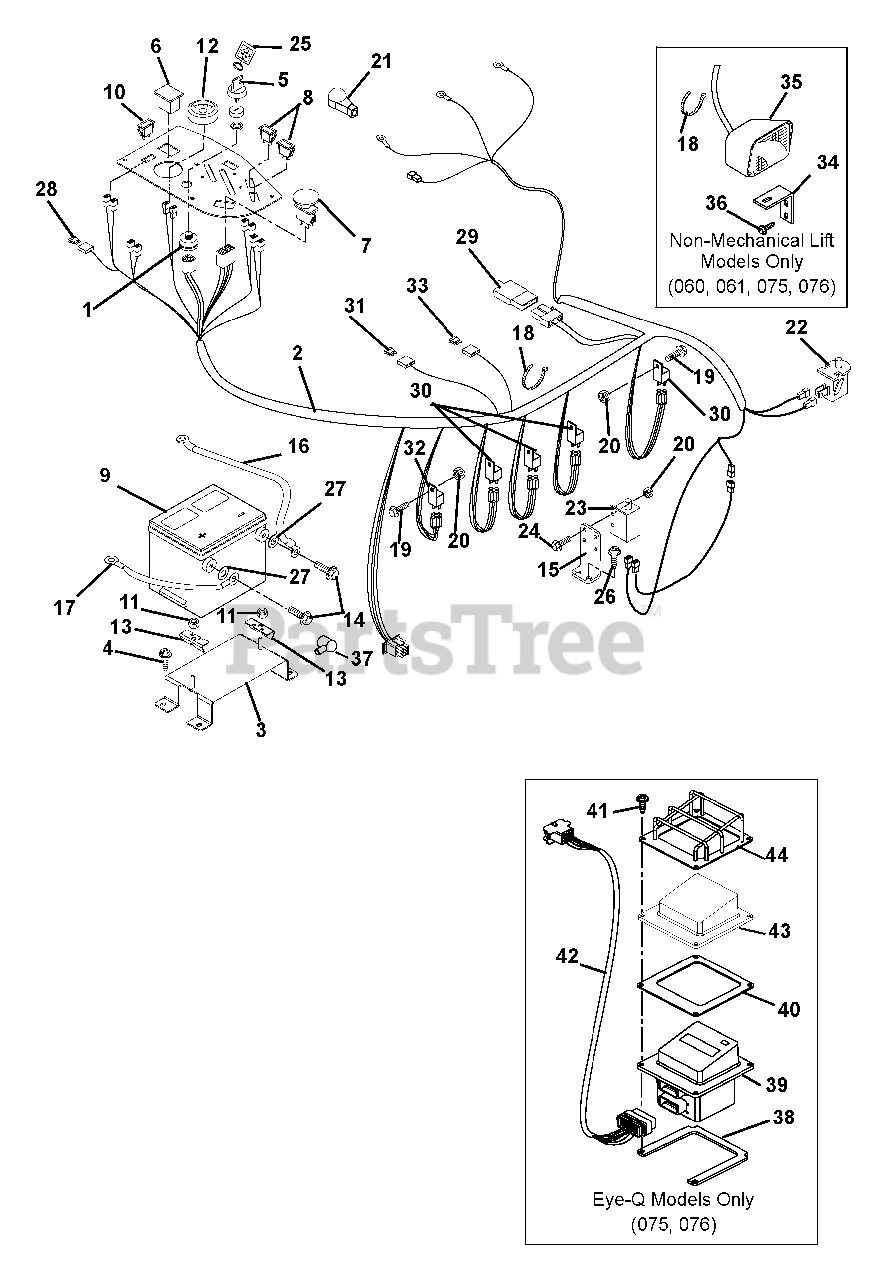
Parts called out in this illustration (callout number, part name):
1	Switch, Ignition (Diesel)
2	Harness, Wiring (Diesel)
3	Weldment, Battery Support
4	Screw-Tapping .38-16 x .75 Hex Washer Head
5	Key-with Cap
5	Ignition Key Set
6	Plug
6	Hour Meter
7	Switch-Clutch With Retainer Ring
8	Light-Indicator Kit
9	Battery with Tube
10	Switch, Light
10	Switch, Blank
11	Nut-Locking-Top-Flange .31-18
12	Gauge, Temperature
13	Bracket, Battery Hold-Down
14	Bolt-Hex .25-20 x .75 Grade 5
15	Mount, Safety Switch
16	Positive Cable
17	Cable, Negative Battery
18	Cable Tie
19	Screw-Machine 10-24 x .75 Hex Washer Head
20	Nut-Locking-Nylon 10-24 With Insert
21	Eyelet Terminal Boot
22	Switch, Snap Mounting (N.O.)
23	Switch-Single Pole
24	Screw-Machine 10-24 x .75 Hex Washer Head
25	Key Chain
26	Screw-Tapping .25-20 x .50 Hex Washer Head
27	Washer-Flat-Steel .406 x 1.00 x ..083
28	Fuse, ATO 15 Amp
29	Diode, Connector Shell
30	Relay
31	Fuse, ATO 30 Amp
33	Fuse, ATO 60 Amp
34	Bracket, Headlight Mounting
35	Headlight
36	Screw-Tapping .38-16 x .50 Hex Washer Head
37	Boot, Eyelet Terminal
38	Spacer, Enclosure Mounting (Bottom)
39	Assembly, Eye-Q
40	Gasket, Eye-Q
41	Screw, Machine 10-24 x 1.0 Slotted Pan Black
42	Harness Jumper (Eye-Q)
43	Guard, Element
44	Guard, Vinyl Eye-Q
